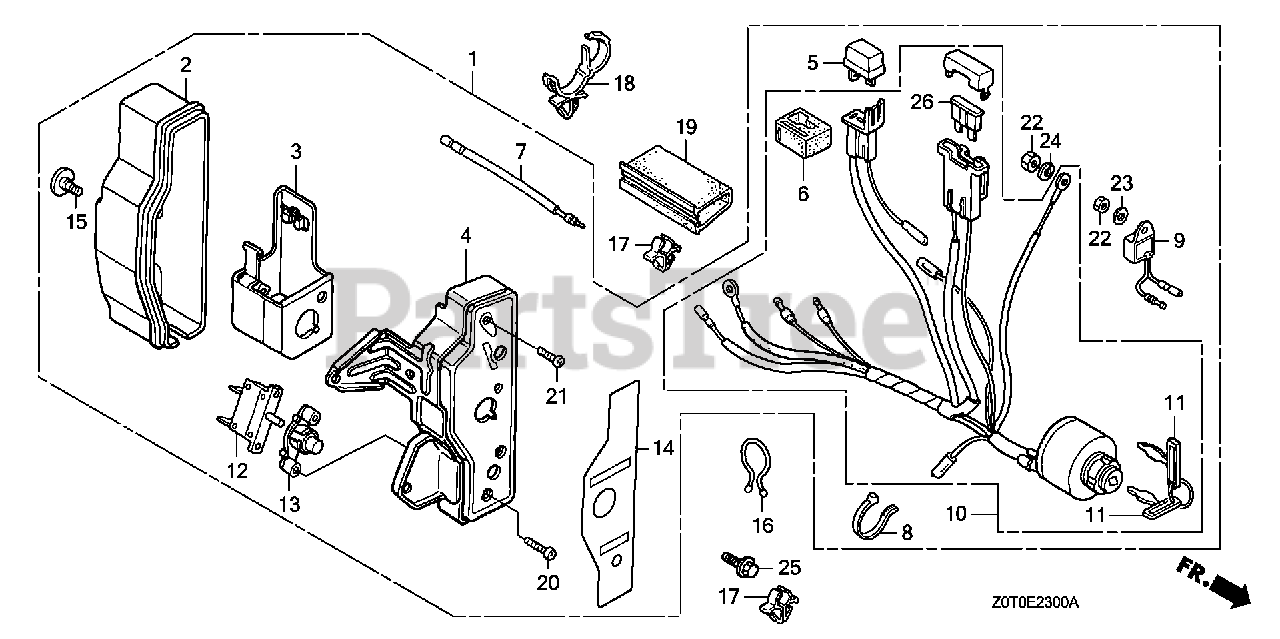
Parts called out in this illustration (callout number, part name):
1	BOX ASSY., CONTROL *R280* (EXP-ALERT) (POWER RED)
2	CASE, CONTROL
3	BRACKET, CASE MOUNTING
4	PANEL, CONTROL *R280* (POWER RED)
5	RECTIFIER ASSY., SILICON (SHINDENGEN)
6	SUSPENSION, CONNECTOR
7	SUB-WIRE HARNESS
9	ALERT UNIT, OIL
10	SWITCH ASSY., COMBINATION
11	KEY (HONDALOCK)
12	PROTECTOR, CIRCUIT (1.0A)
13	LENS ASSY., PROTECTOR
14	MARK, CONTROL BOX (EXP)
15	SCREW, SPECIAL (6X12)
16	CLIP, PURSE LOCK
17	CLIP, CORD
18	STRAP, WIRE HARNESS (25MM) (BLACK)
19	TUBE, FASTENER (30MM)
20	SCREW, PAN (3X12)
21	SCREW, PAN (4X12)
22	NUT, HEX. (4MM) (SOURCE: VINTAGE PARTS INC.)
23	WASHER, PLAIN (4MM)
24	WASHER, SPRING (4MM)
25	BOLT, FLANGE (6X10)
26	FUSE, BLADE (5A)
